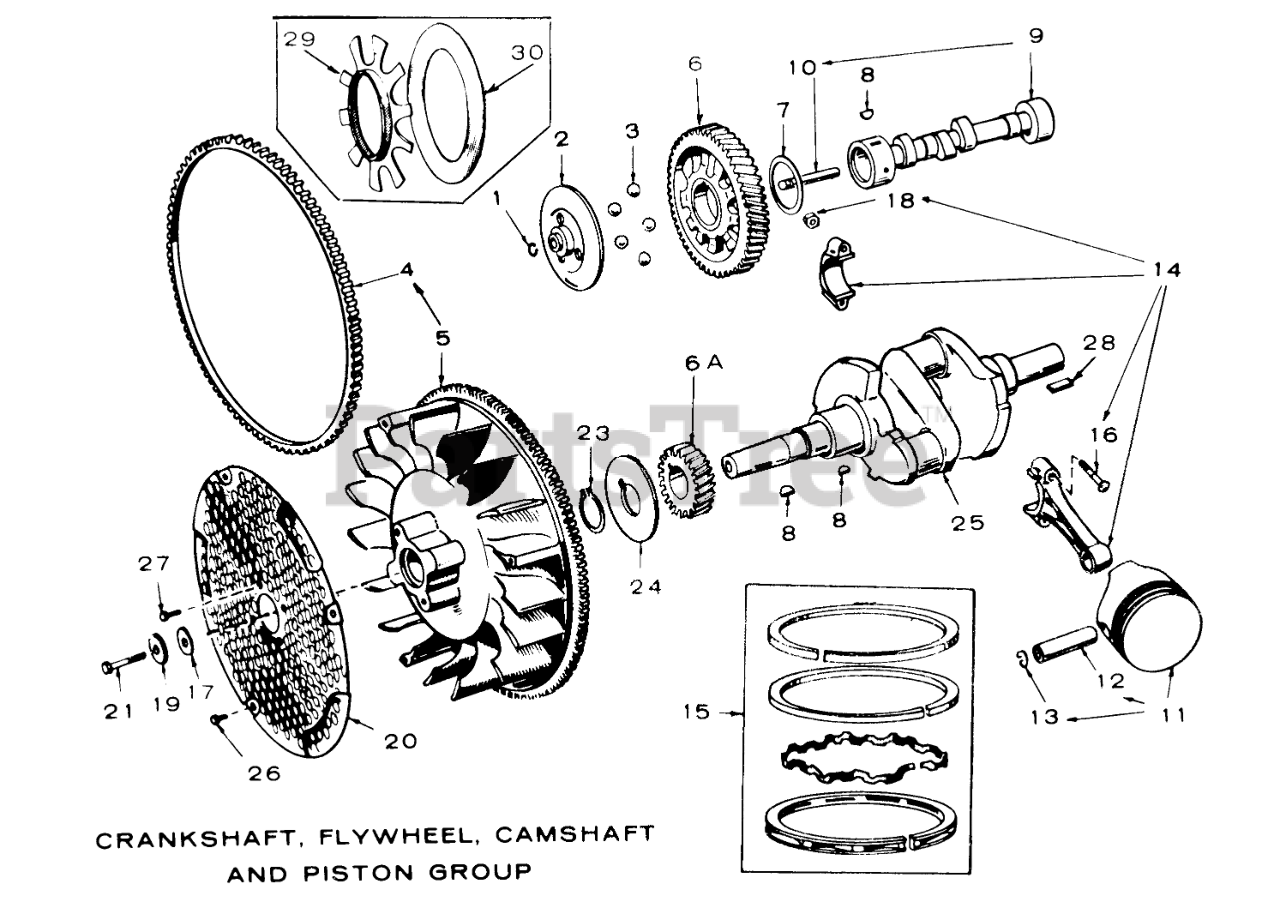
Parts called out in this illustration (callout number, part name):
1	Ring-Camshaft Center Pin
2	Governor Cup
3	Governor Fly Ball
4	Ring Gear
5	Flywheel (Includes Ring Gear and Magnet Ring)
6	Camshaft Gear
6A	Crankshaft Gear
7	Camshaft Thrust Washer
8	Key
9	Camshaft (Includes Center Pin)
10	Camshaft Center Pin
11	PISTON AND PIN (INCLUDES RETAINING RINGS)
12	Wrist Pin
13	Lock
14	ROD ASSEMBLY, CONNECTING
15	RING SET, PISTON
16	Connecting Rod Bolt (Special)
17	Washer 7/16
18	Lock Nut-Connecting Rod
19	Lockwasher 7/16 Flywheel
20	Flywheel Guard
21	Hex Bolt
23	Retaining Ring
24	Washer-Crankshaft Gear
